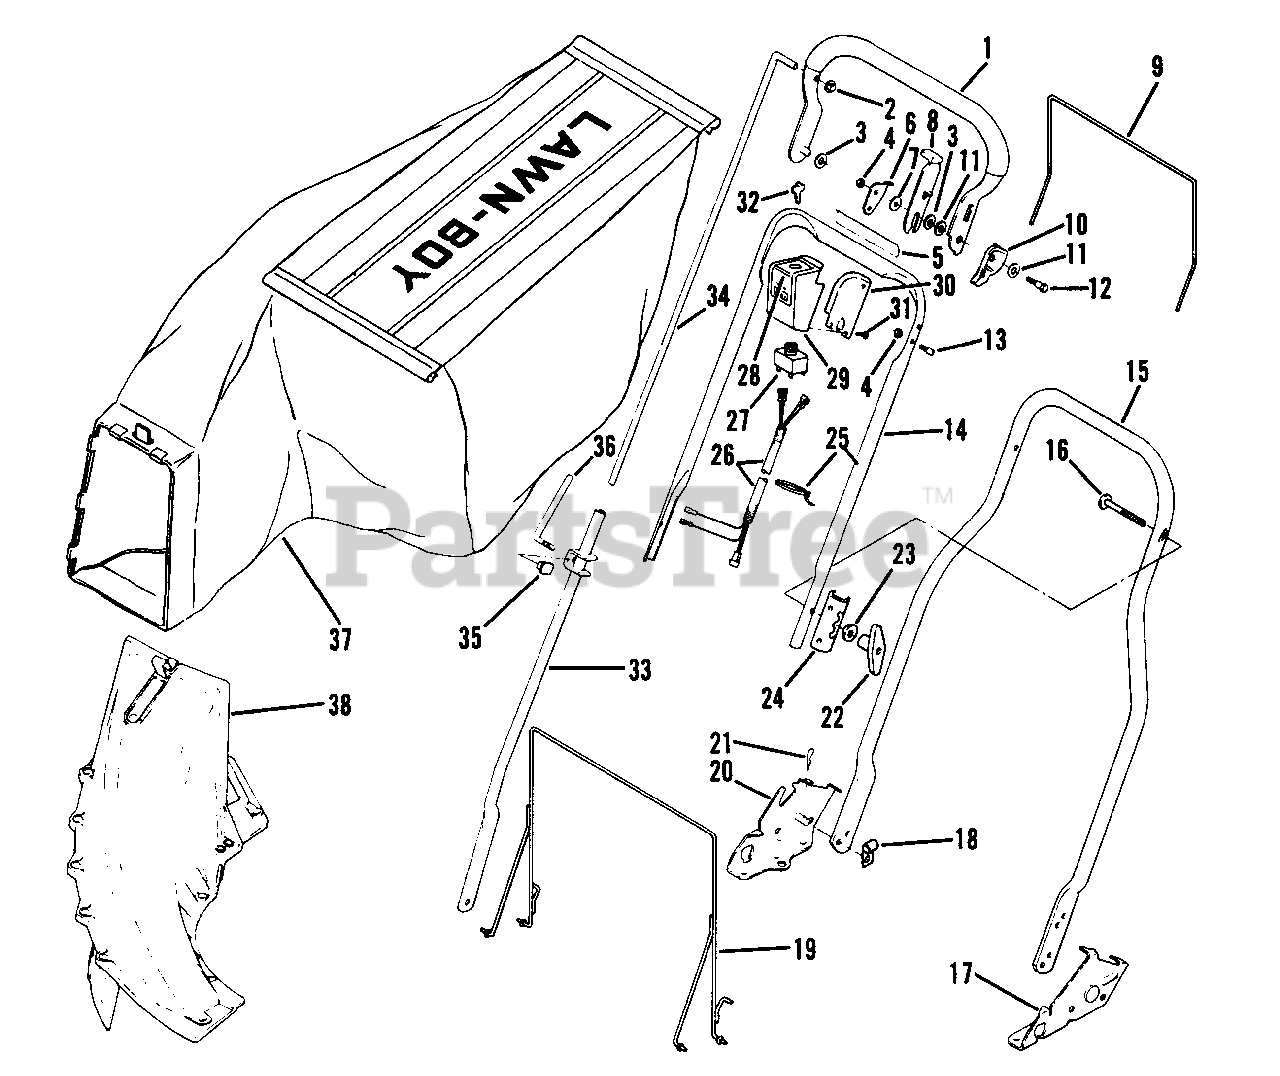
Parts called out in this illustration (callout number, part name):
1	Handle & Grip Assembly
2	Palnut
3	Washer
4	Nut-Lock
5	Decal
6	Stop-Handle
7	Washer
8	Lever-Lockout
9	Hanger-Rear
10	Guard-Lever
11	Washer
12	Bolt-Shoulder
13	Screw-Stop
14	Handle-Center
15	Handle Section-Bottom
16	Screw
17	Bracket-Handle-L.H.
18	Clamp
19	Hanger Assembly-Front
20	Bracket-Handle-R.H.
21	Hair Pin
22	Knob
23	Washer-Curved
24	Bracket-Rear Hanger
25	Cable Tie
26	Wire Harness Assembly Switch
27	Key Switch
28	Decal-Switch
29	Housing-Switch
30	Retaining Plate-Switch Housing
31	Screw
32	Key-Switch
33	Control Lever Assembly
34	Control Rod
35	Nut
36	Screw
37	Bag & Deflector Assembly
38	Chute Assembly
